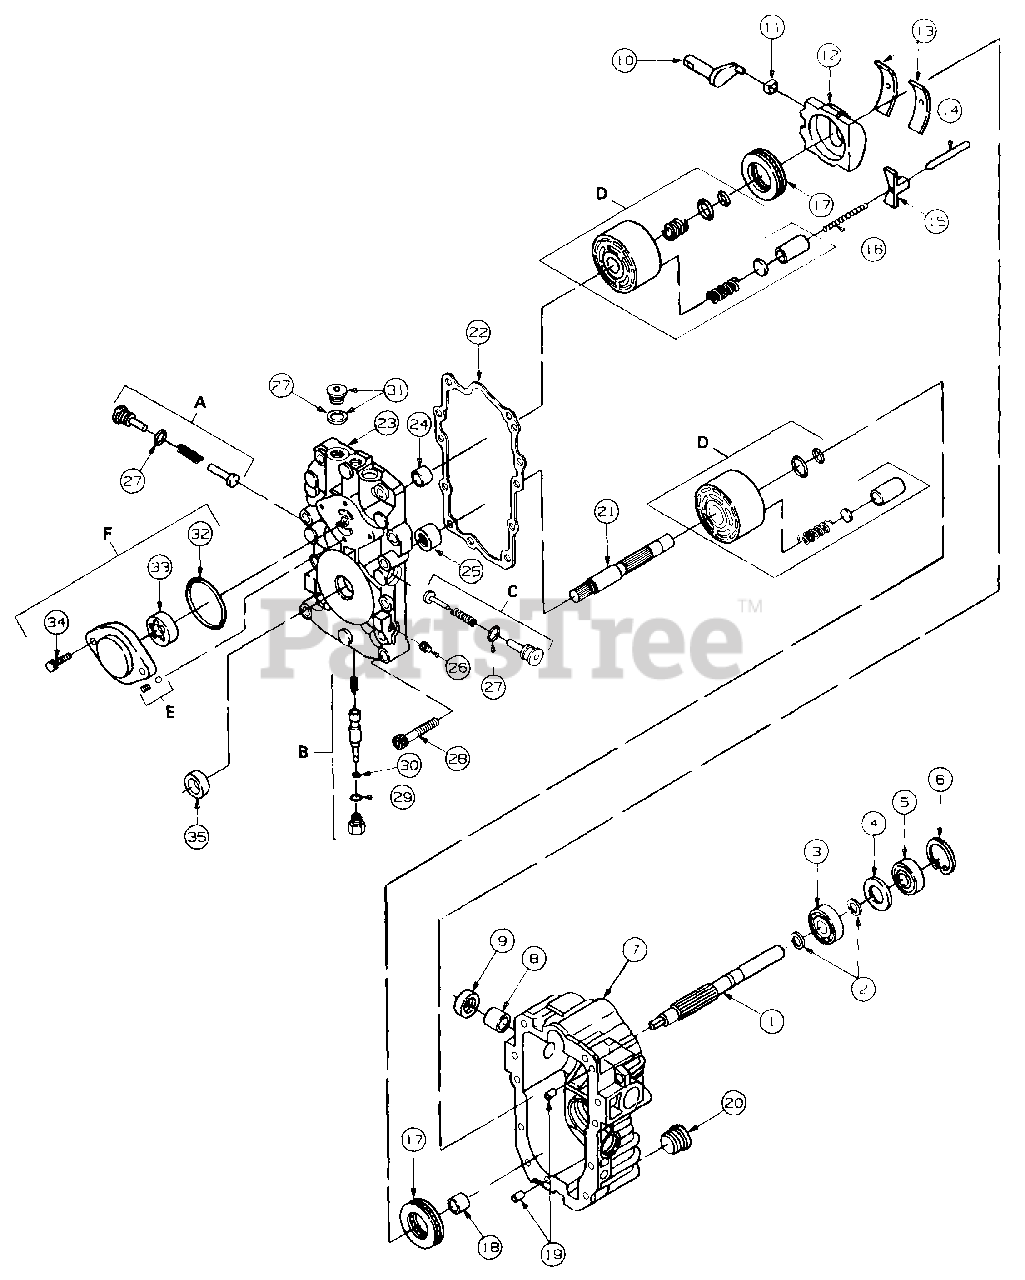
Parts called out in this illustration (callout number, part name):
1	Shaft, Pump
2	Ring, Retaining
3	Bearing, Ball
4	Spacer
5	Seal, Lip
6	Ring, Retaining
7	Housing Assy
8	Bearing, Journal
9	Seal, Lip
10	Arm, Trunnion
11	Guide, Slot
13	Bearing, Cradle
15	Leveler, Swashplate
16	Spring, Leveler
17	Bearing, Thrust
18	Bearing, Journal
21	Shaft, Motor
22	Gasket, Center Section
23	Center Section Assy
24	Bearing, Journal
25	Bearing, Needle
27	O-Ring
28	Screw, Socket Hd
29	O-Ring
30	O-Ring
32	O-Ring
33	Gerotor Assy
34	Screw, Socket Hd
35	Seal, Lip
A	Kit, Check Valve
B	Kit, Bypass Valve
C	Kit, Orificed Check Valve
D	Kit, Cylinder Block
E	Kit, Charge Relief Valve
F	Kit, Charge Pump
